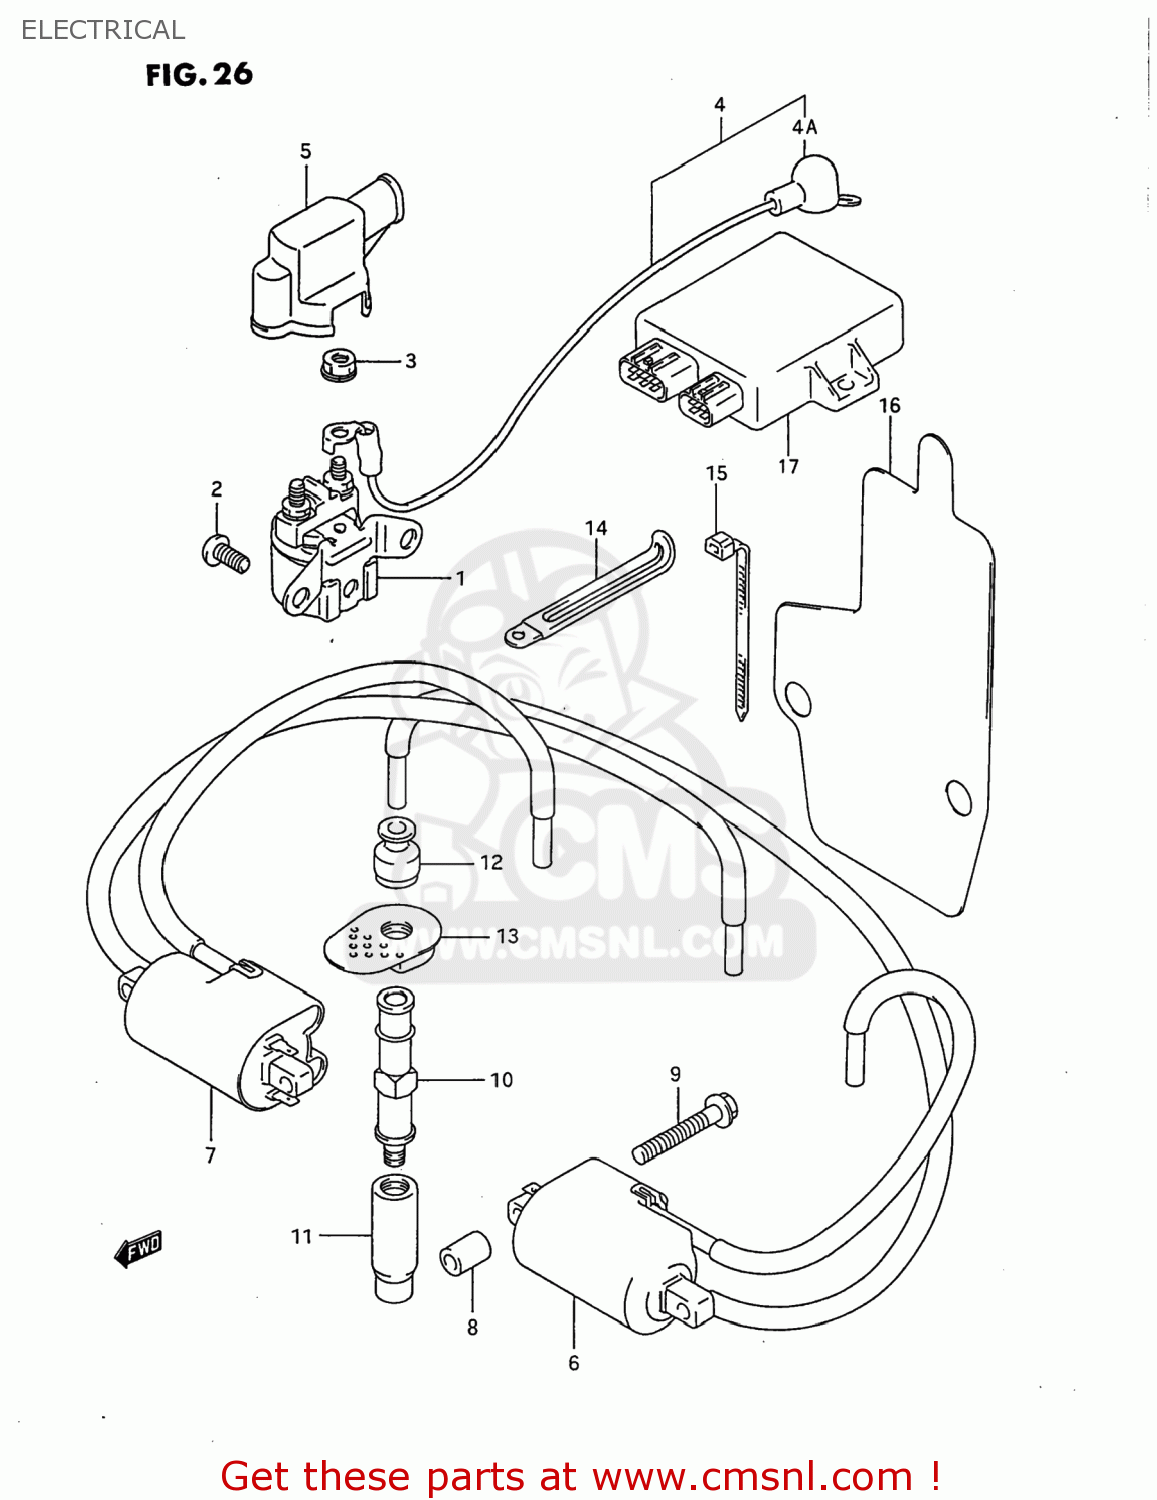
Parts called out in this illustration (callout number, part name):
1	RELAY ASSY,STARTING MOTOR
2	SCREW
3	NUT
4	WIRE,STARTER MOTOR LEAD
4A	CAP,STARTER MOTOR LEAD
5	CAP,STARTER RELAY
6	COIL ASSEMBLY,IGNITION NO
7	COIL ASSEMBLY,IGNITION NO
8	SPACER(6.2X12X16)
9	BOLT (6X45)
10	CAP,SPARK PLUG
11	SEAL,SPARK PLUG
12	SEAL,HIGH TENSION CORD
13	COVER,SPARK PLUG CAP
14	CLAMP(L:65)
15	CLAMP L:165
16	COVER,IGNITION COIL
17	IGNITOR ASSY
